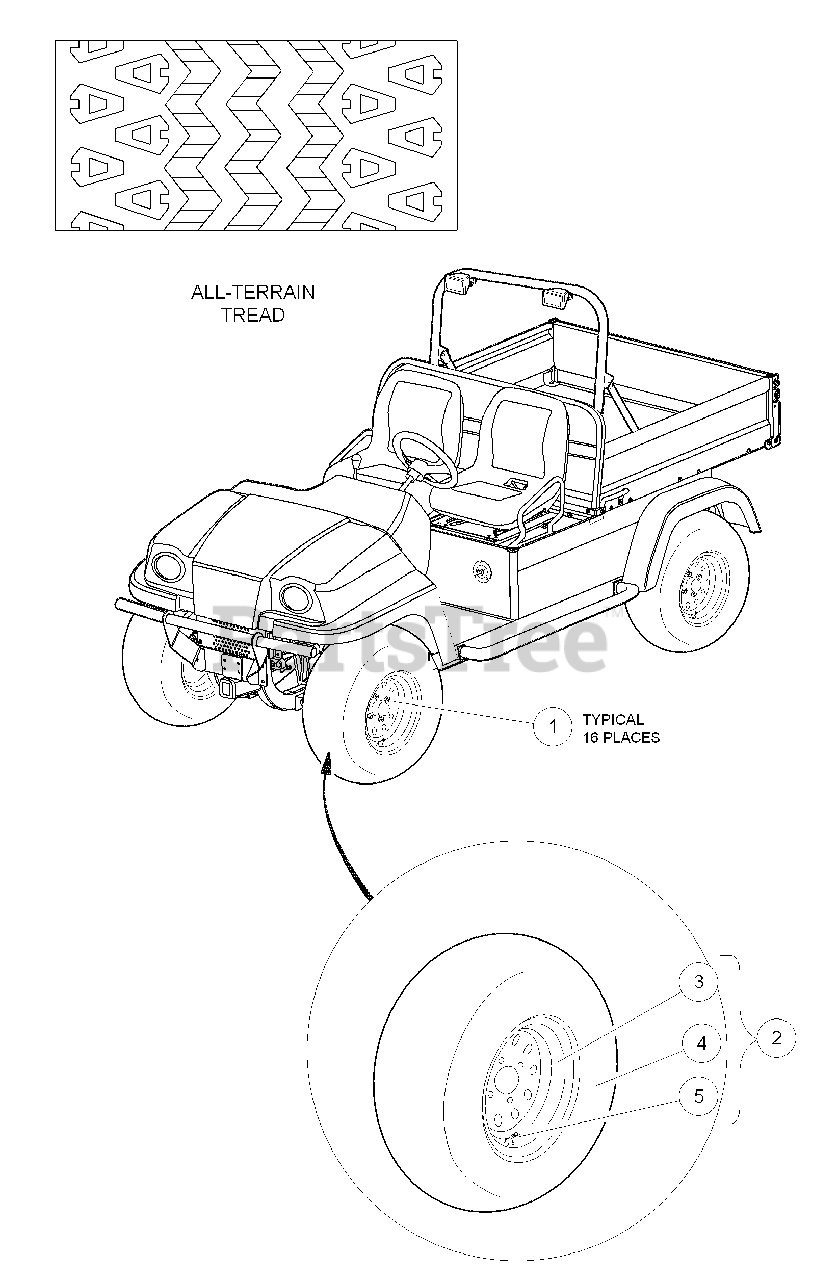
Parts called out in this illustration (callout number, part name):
1	.500-20 Unf Lug Nut
2	Gray Tire Assembly, HDAT Tread
3	WnGGl Rim, Gray
4	Tire, HDAT
5	Valve Stem
